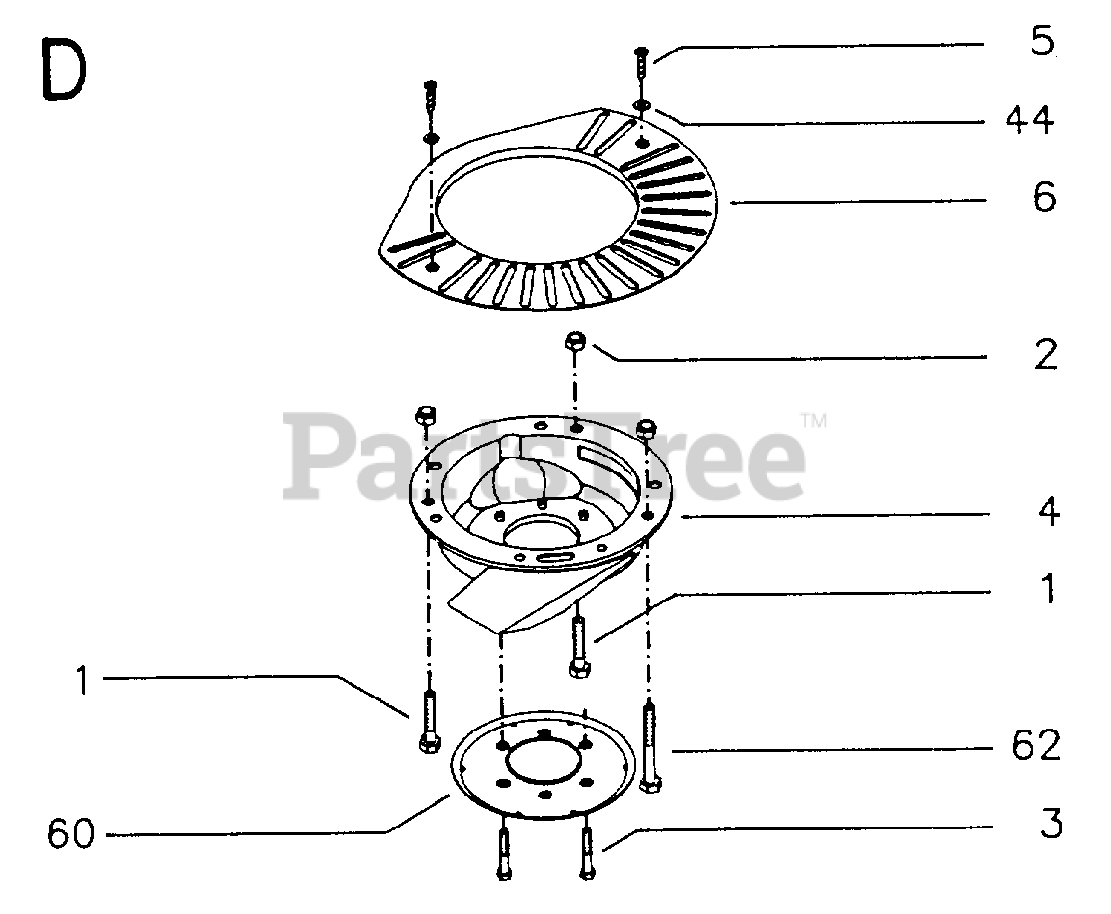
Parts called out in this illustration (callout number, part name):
2	LOCKNUT M8
4	REPL BY 516 69 84-11
6	CENTER PLATE
44	WASHER
